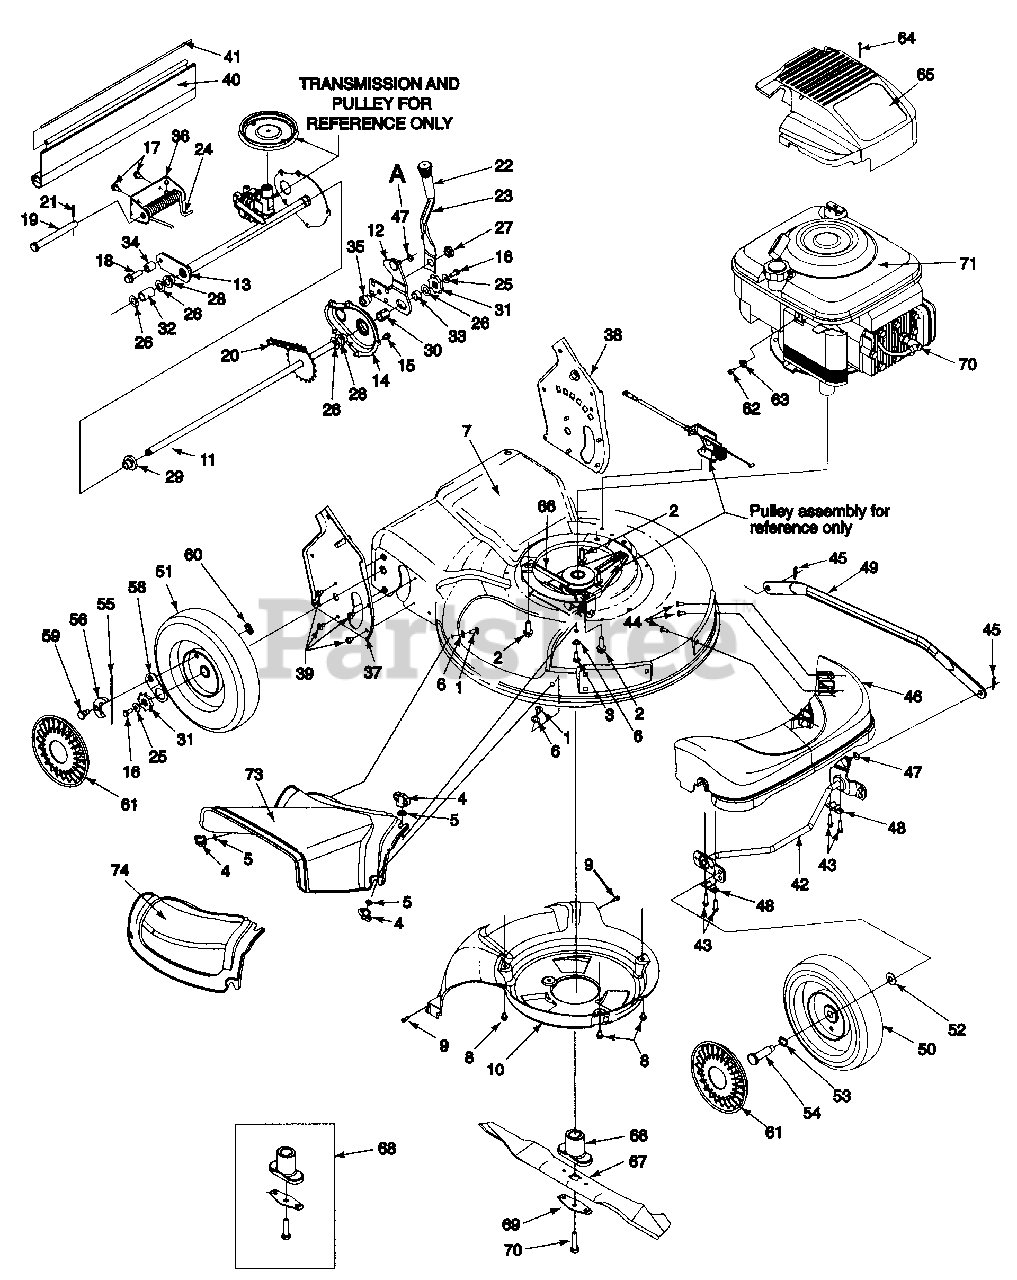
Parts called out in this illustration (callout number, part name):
1	Scr. Carr. 1/4-20 x .62
2	Scr. TT:3/8-18:1.00
3	Scr. 1/4-20 x .750
4	Wing Nut 1/4-20
5	Nut, Push .25 I.D. x .50 O.D.
6	Wash. F1. .334 I.D. x .62 x .03
8	Scr. TT. 1/4-20 x .375
9	Scr. HL. 1/2-14 x .750
10	Baffle
11	Rear Axle Ass'y
16	Cap Screw HH 1/4-20 x .620
17	Scr. AB 1/4-14 x .825
18	Scr. 3/8-16 x 1.25
19	Clevis Pin .50 Dia. x 4.82 Lg.
20	Chain-Endls. #48 .500P x 24L
21	Cotter Pin .125 O.D. x .75
23	Spring Lever
24	Torsion Spring
25	Bell Wash. .285 x .75 x .082
26	Fl. Wash. .508 I.D. 1.000 x .
27	Nut Shld. .825 Dia. x .165 Lg.
28	Hx .Flg. Brg. .506 I.D. x .590 L.
29	Hx .Flg. Brg. .506 I.D. x .715 L.
30	Hx . Slv. Brg. .504 I.D. x .830 L.
31	Wheel Rachet
32	Spa. .550 I.D. x .750 O.D.
33	Spa. .51 I.D. x .70 O.D. x 38 L.
34	Spa. .385 x .624 x .700
35	Shld. Spa. .385 I.D. x .715 Lg.
38	Handle Brkt. Ass'y. L.H.
39	Scr. AB 1/4-14 x .500
40	Trail Shield
41	Trail Shield Wire
42	Fr. Axle Ass'y.
43	Hx Scr. Wash Hd. Hi.-Lo.
44	Scr. Torx, Truss Hi.-Lo.
45	Cotter Pin .072 x 1.12 Lg.
46	Fr. Axle Cover
47	Bowed Washer
48	Bush. Block .505 Dia. x .62
49	Control Arm
50	Wheel 8 x 2 Link Gray
51	Wheel 9 x 2 Link Gray, Sleeve
52	Spr. Wash. .401 x .870 x .063
53	Wave Wash .510 x .750 x .017
54	Shldr Scr .498 x 1.445 x 3/8-16
55	Spring, Ratchet, Plastic
57	Pawl - L.H.
58	Ratchet Pawl Plate
59	Hubcap - Gray
60	Top Lock Tab Weld Nut 1/4-20
61	Hubcap - Gray
62	Screw .620 Hx . Slt. Wsh.
63	Casing Clamp, Throttle
64	Scr. Hi-Lo #10 x 1.25
65	Shroud - Gray
66	Belt
67	21" Mulching Blade
68	Blade Adapter Kit
69	Blade Bell Support
70	Hex Bolt 3/8-24 x 2.5"Lg.
71	Engine
72	Spark Plug Insulator
73	Side Discharge Chute
74	Mulch Cover
75	Scr. Hex . 5/15-18
